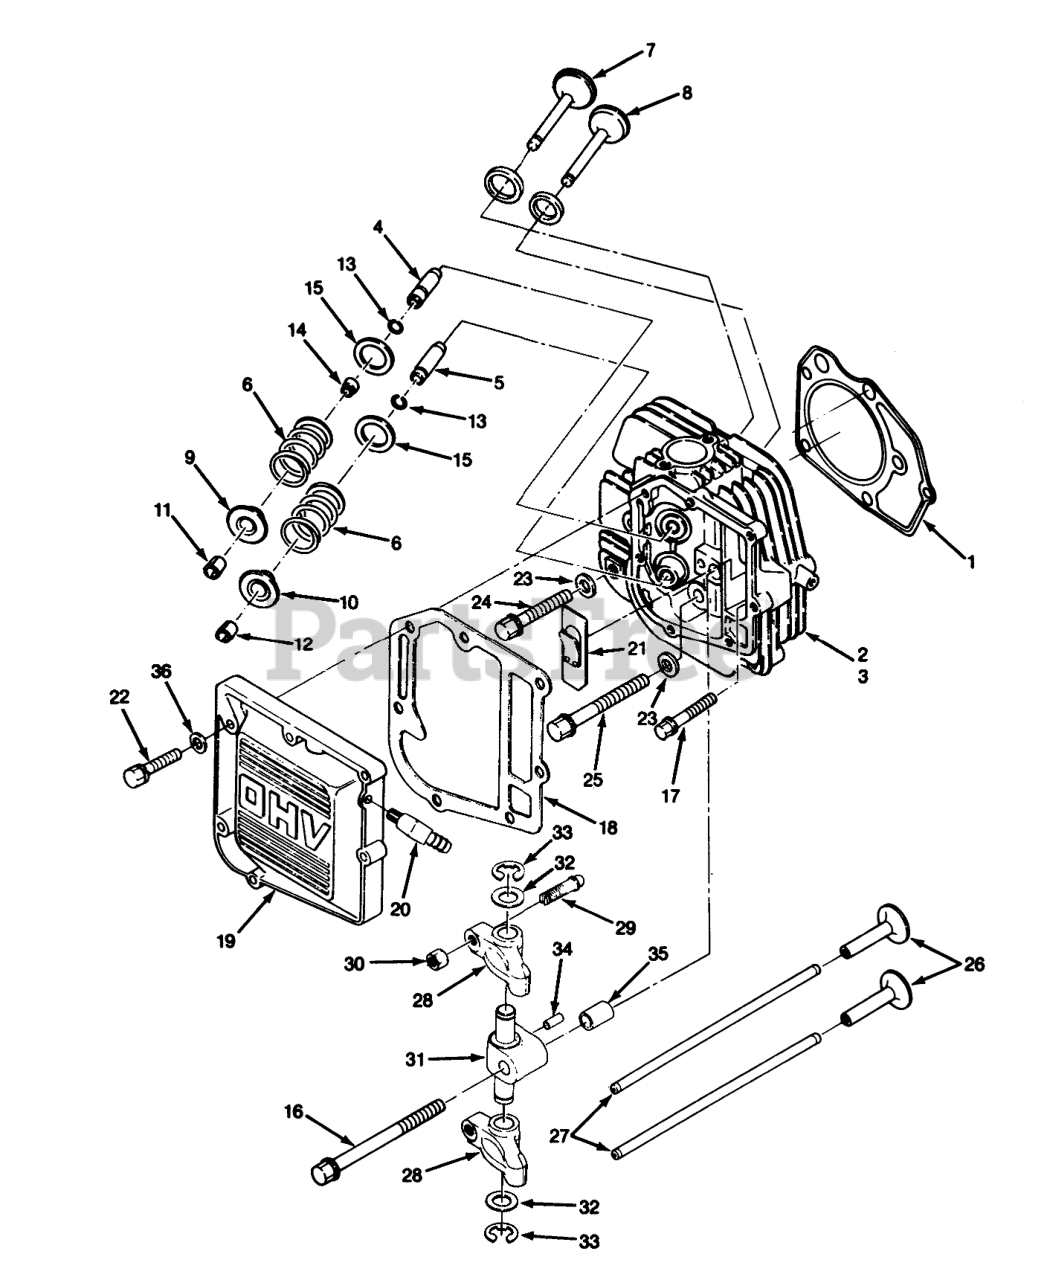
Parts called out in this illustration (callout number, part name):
1	GSKT-CYL HEAD
2	Cylinder Head Assembly (Incl. Ref. #4-15)
3	Cylinder Head Assembly (Incl. Ref. #4-5)
4	GUIDE-VALVE INTAKE
5	GUIDE-VALVE EXHAUST
6	SPRING-VALVE
7	VALVE-INTAKE MKD IN
8	VALVE-EXHAUST MKD EX
9	RETAINER-VLV SPG IN
10	RETAINER-VLV SPG EX
11	Lock-Intake
12	LOCK-VALVE EXHAUST
13	RING-VALVE GUIDE
14	Seal-Intake
15	WASHER-VALVE SPRING
16	BLT-CYL HD M10X125MM
17	BLT-CYL HD M8X50MM
18	Seal
19	Cover-Valve
20	ELBOW-90 DEGREES
21	BREATHER
22	SCRW-CP SH M6X25MM
23	WASHER-FLAT M10
24	BLT-CYL HD M10X66MM
25	BLT-CYL HD M10X66MM
26	TAPPET
27	ROD-PUSH
28	Rocker Arm Assembly (Incl. Ref. #29-30)
29	SCRW-LASH ADJUSTING
30	NUT-LASH ADJUSTING
31	SHAFT-ROCKER ARM
32	Rocker Arm Washer
33	CLIP-RETAINER
34	PIN-DOWEL
35	PIN-DOWEL HOLLOW
36	Washer
